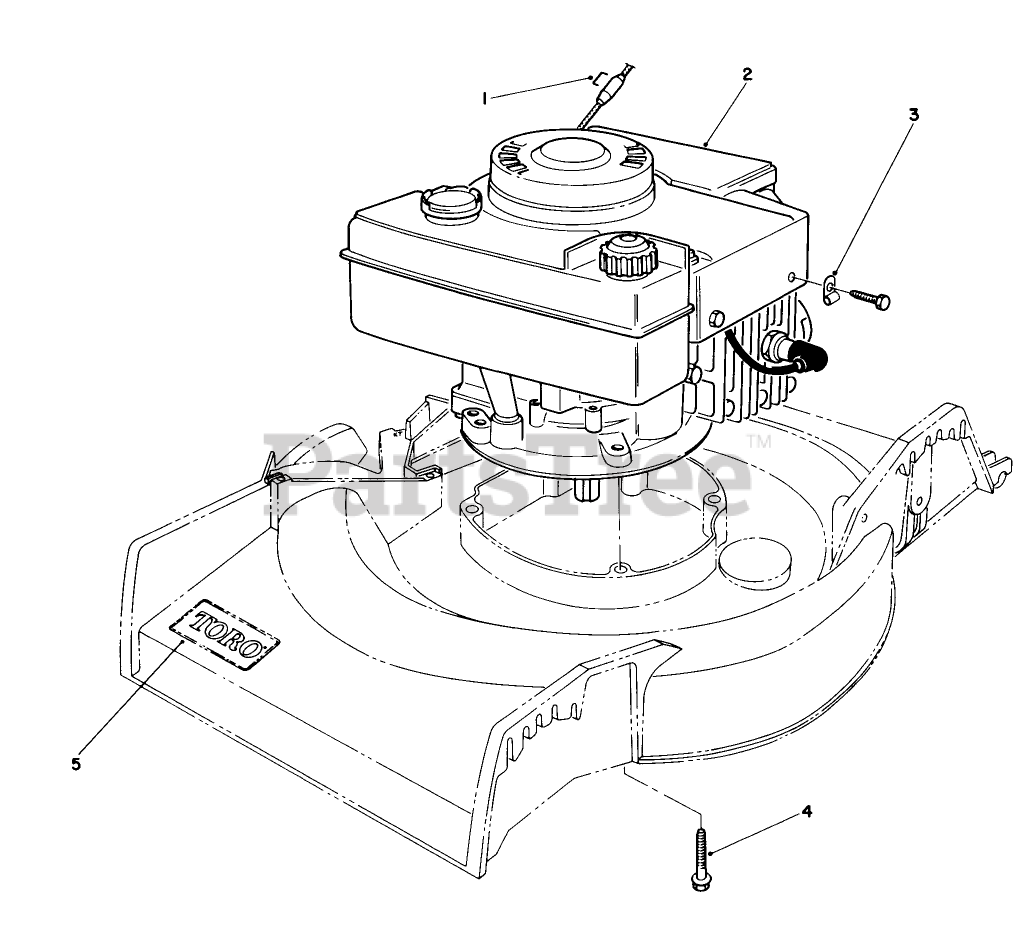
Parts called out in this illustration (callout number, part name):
1	Staple
2	Engine
4	3/8-16 X 2-3/4 CAPSCR
5	DECAL
